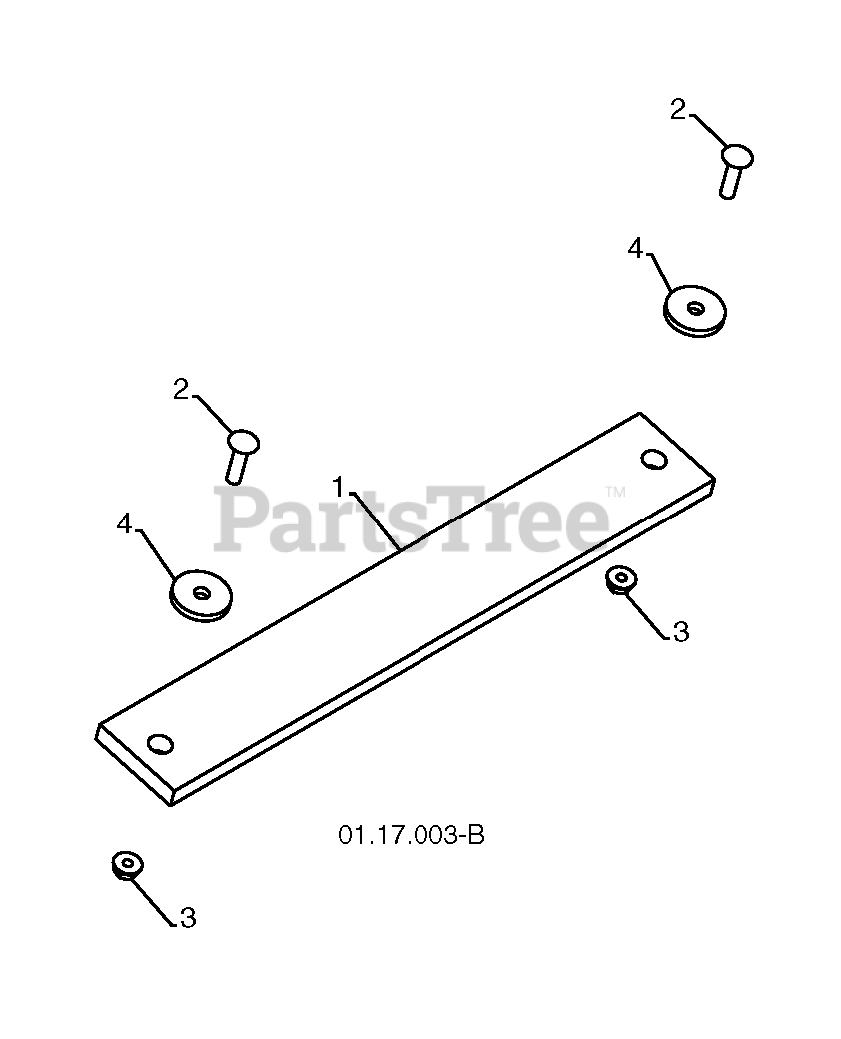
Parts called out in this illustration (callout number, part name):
1	WEIGHT AUGER HOUSING 30
2	BOLT.CARRIAGE.5/16-18
3	NUT.LOCK.5/16-18
4	WASHER.FLAT.34X1.38X22
